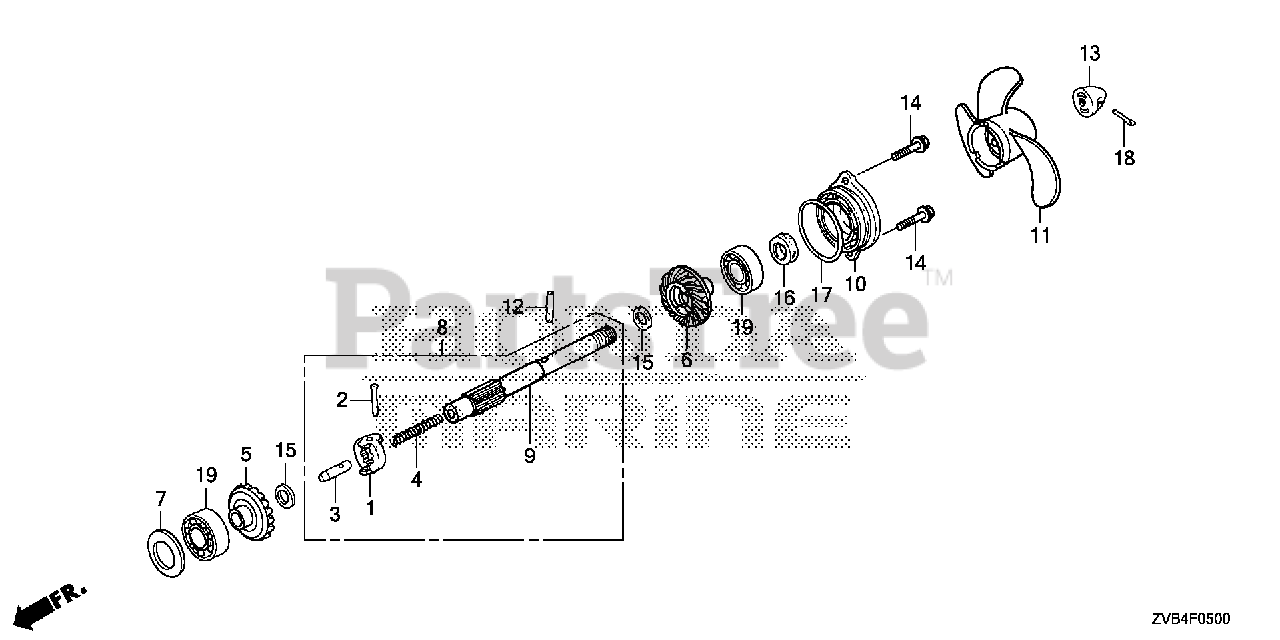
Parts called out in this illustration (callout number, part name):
1	SHIFTER, CLUTCH
2	PIN, SHIFTER (3X26)
3	SLIDER, SHIFT
4	SPRING, SHIFT
5	GEAR, BEVEL (F)
6	GEAR, BEVEL (R)
7	SHIM B, GEAR (0.10MM)
8	SHAFT, PROPELLER
9	SHAFT, PROPELLER
10	HOLDER, PROPELLER SHAFT *NHB14M* (AQUA MARINE SILVER METALLIC)
11	PROPELLER, THREE-BLADE (7-7/8X6-3/4) *NH283* (STIN GRAY)
11	3AL 7 7/8 5 7/8
11	PROPELLER, THREE-BLADE (7-7/8X5-7/8) *NH283* (STIN GRAY)
11	PROPELLER, THREE-BLADE (7-1/4X5-1/2) *NH283* (STIN GRAY)
11	PROPELLER, THREE-BLADE (7-7/8X7-1/2) *NH283* (STIN GRAY)
11	PROPELLER, THREE-BLADE (7-7/8X8-1/4) *NH283* (STIN GRAY)
12	PIN, SHEAR
13	CAP, PROPELLER
14	BOLT, FLANGE (6X16)
15	WASHER (13MM)
16	SEAL, WATER (13MM) (ARAI)
17	O-RING (52MM)
18	PIN, SPLIT (3.0)
19	BEARING, RADIAL BALL (6004)
